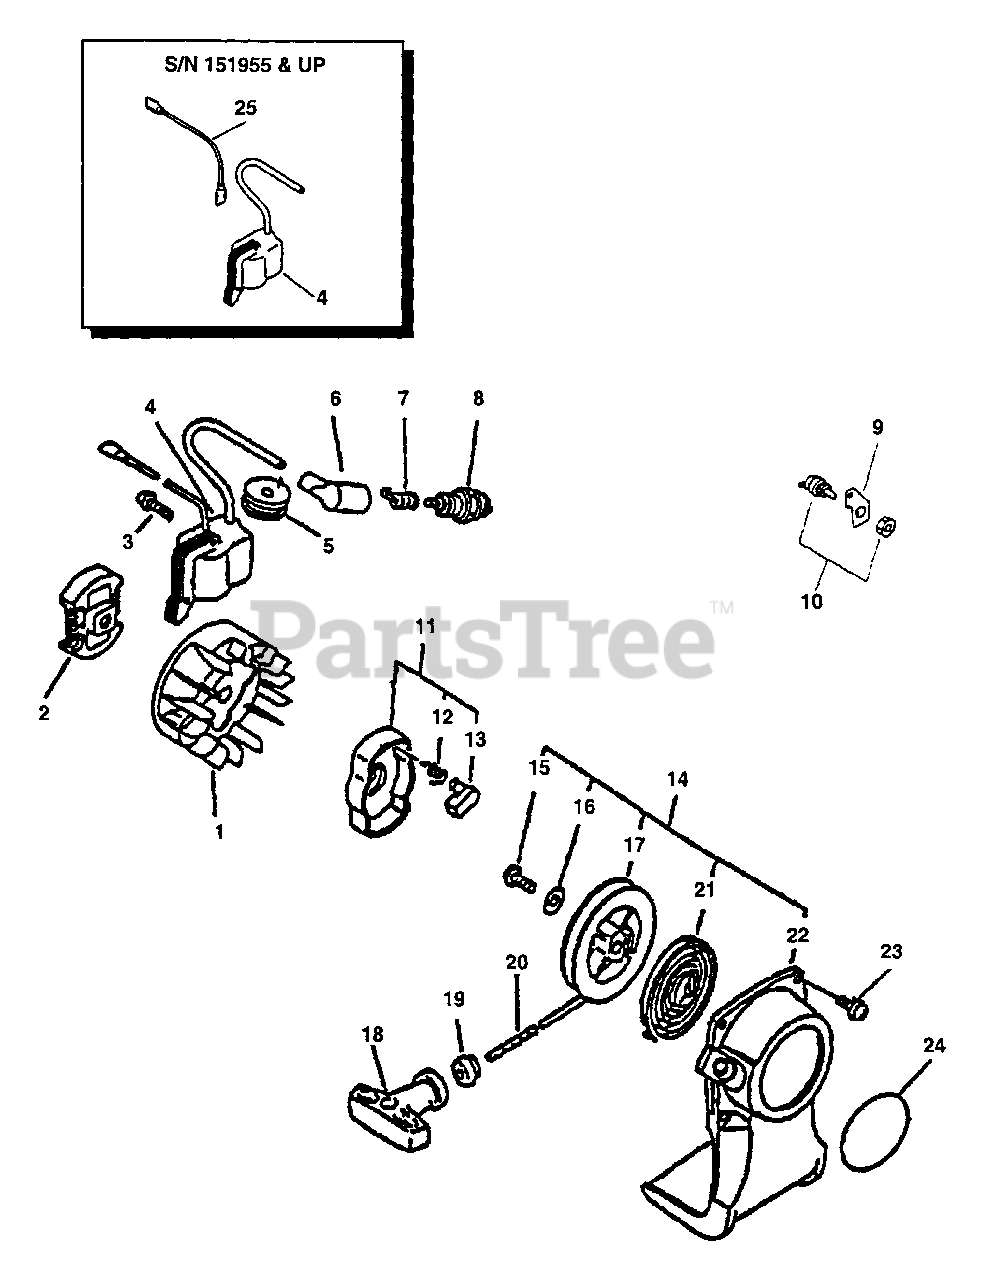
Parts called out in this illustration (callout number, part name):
1	FLYWHEEL
2	CLUTCH ASSY
3	SCREW 4×22
4	COIL, IGNITION
6	CAP, SPARK PLUG
7	TERMINAL, SPARK PLUG
8	SPARK PLUG - BPM7A
8	SPARK PLUG - BPMR7A
9	BRACKET, SWITCH
10	SWITCH, ON-OFF
11	PAWL ASSY, STARTER
12	SPRING, RETURN
13	PAWL, STARTER - BLACK
14	STARTER ASSY
15	SCREW
16	WASHER
17	REEL, ROPE
18	GRIP, STARTER
19	GUIDE, ROPE
21	SPRING, RECOIL
22	CASE, STARTER
23	BOLT 4×16
24	LABEL, ECHO
25	LEAD - GROUND
